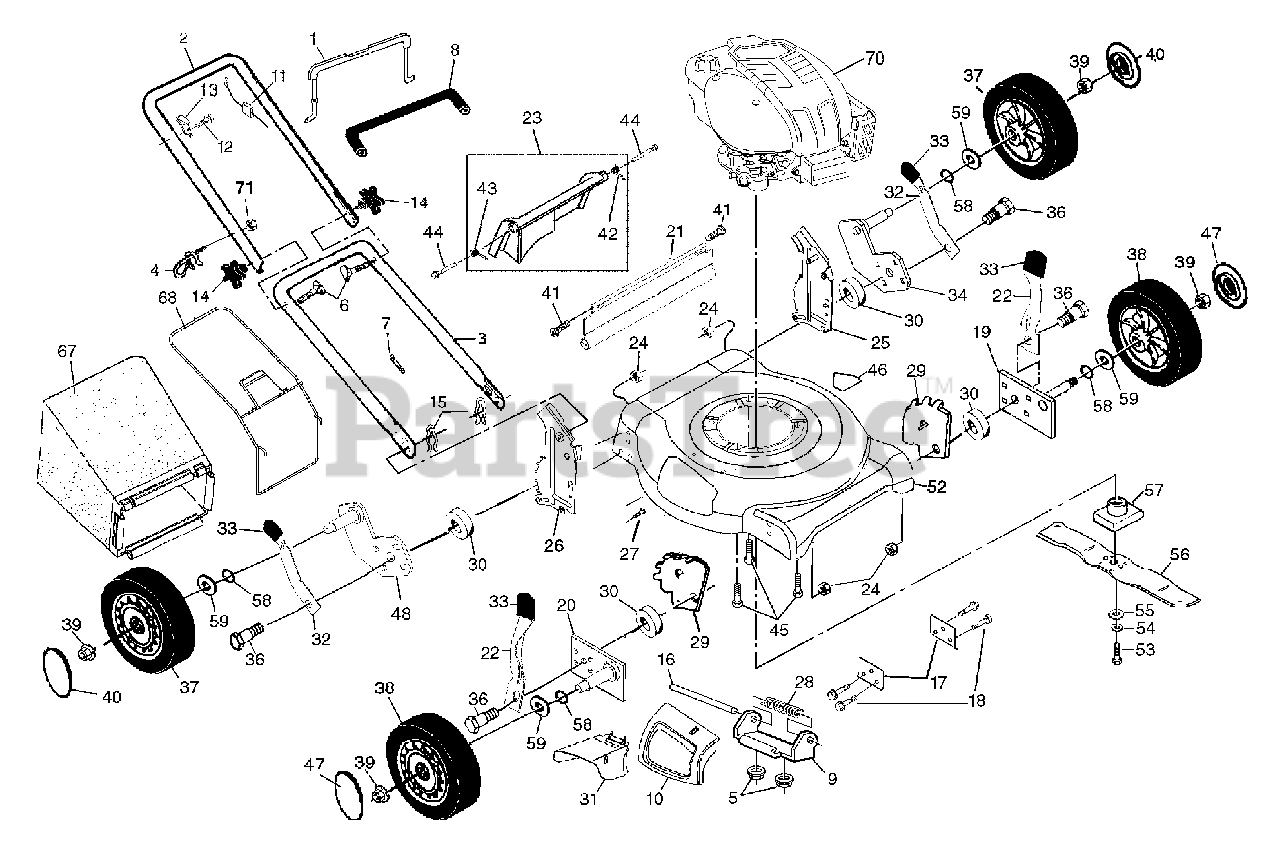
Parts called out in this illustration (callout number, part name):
1	Control Bar
2	Upper Handle, with Grip
3	Lower Handle
4	Rope Guide
5	Locknut 1/4-20
6	Handle Bolt
7	Wire Tie
8	Grip, Foam
9	Hinge Bracket
10	Mulcher Door
11	Engine Zone Control Cable
12	Hex Washer Head Screw
13	Up-Stop Bracket
14	Handle Knob
15	Hairpin Cotter
17	Support Bracket
19	Axle Arm Assembly - LF
20	Axle Arm Assembly - RF
21	Rear Skirt
22	Selector Spring - Front
23	Rear Door Assembly Kit
24	Locknut 5/16-18
25	Handle Bracket Assembly (Left)
26	Handle Bracket Assembly (Right)
27	Screw 1/4-20 x 3/8
28	Hinge Spring
29	Wheel Adjusting Bracket - Front
31	Clip on Discharge Guard
32	Selector Spring - Rear
33	Selector Knob
34	Axle Arm Assembly - LR
36	Shoulder Bolt 5/16-18
37	Wheel Assembly, Rear
38	Wheel Assembly, Front
39	Flanged Locknut
41	Hinge Screw
42	Spring (LH)
43	Spring (RH)
45	Hex Head Thread Rolling Screw 3/8-16 x 1
46	Danger Decal
47	Hubcap
48	Axle Arm Assembly - RR
52	Housing Assembly
53	Hex Head Screw 3/8-24 x 1-3/8 Grade 8
54	Helical Lockwasher
55	Hardened Washer
57	Blade Adapter
58	O-Ring
59	Washer, Flat 3/8
67	Grass Bag
68	Frame, Grass Bag
71	Nut, Hex 1/4-20
